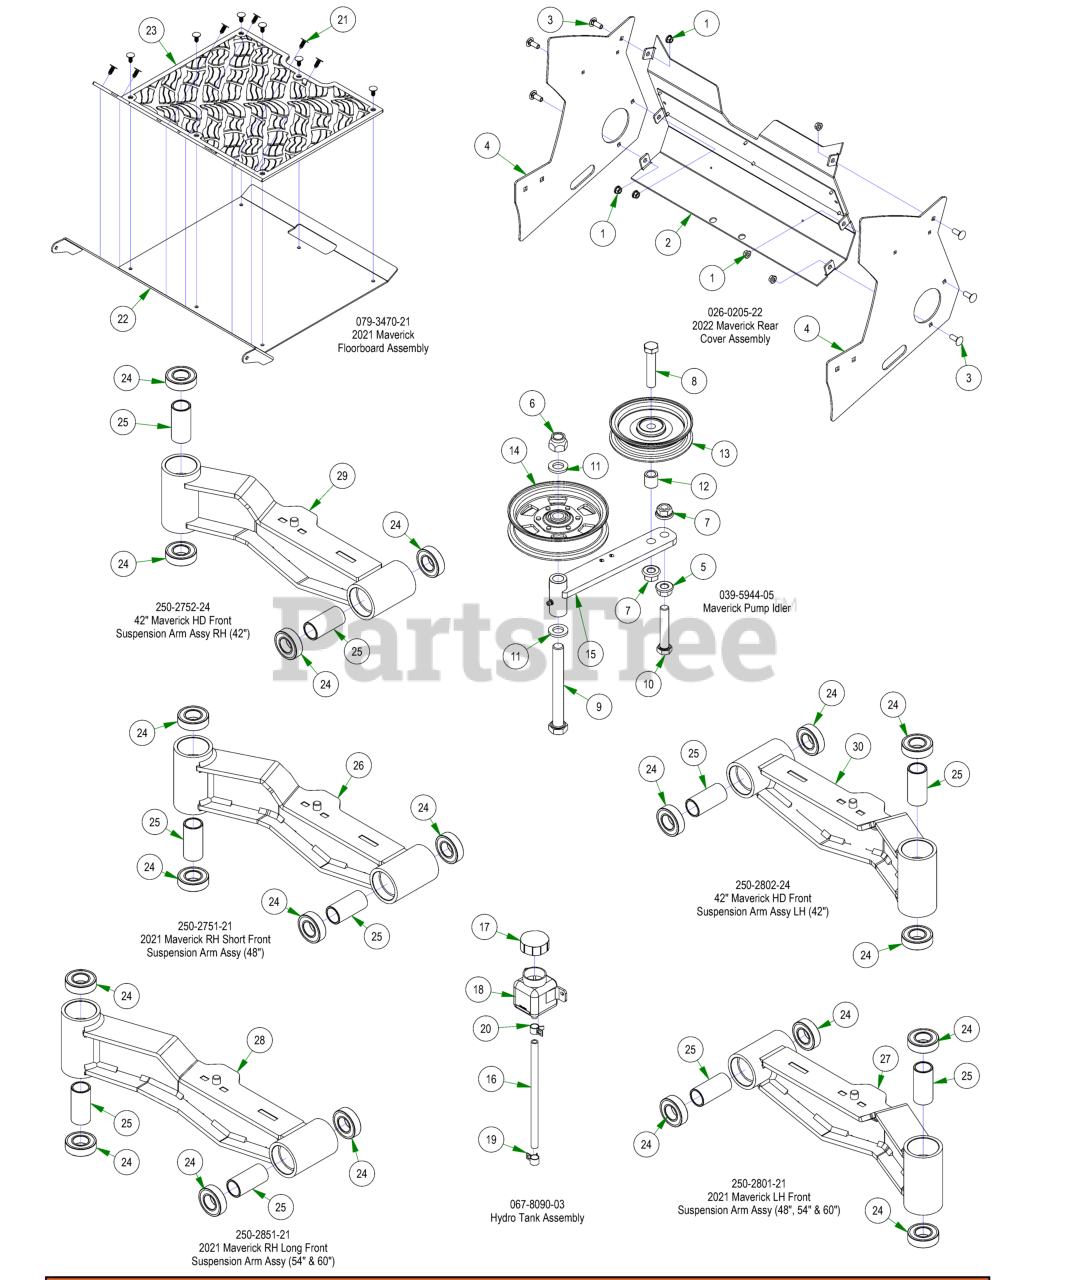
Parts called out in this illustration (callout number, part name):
1	5/16-18 NYLON INSERT FLANGE LOCKNUT ZINC
2	2021 Maverick Rear Cover Assembly
3	3/8-16 X 1 CARRIAGE BOLT (GR.5) ZINC
4	2022 Maverick Rear Cover Side Plate - Painted
5	1/2-13 HEX SERRATED FLANGE NUT HARD/ZINC
6	5/8-11 NYLON INSERT LOCKNUT ZINC
7	1/2-13 NYLON INSERT FLANGE LOCKNUT ZINC
8	1/2-13 X 2-1/2 HEX CAP SCREW GR 5 ZINC
9	5/8-11 X 5-1/2 HEX CAP SCREW (GR.5) ZINC
10	1/2-13 X 2-3/4 HEX CAP SCREW (GR.5) ZINC
11	.635 ID X 1.120 OD X .140 THICK FLAT WASHER NYLON
12	.51 ID X .75 OD X .75 LGTH SOLID SPACER ZINC
13	4 3/4" Idler Pulley
14	5 3/4 Idler Pulley, 5/8 Bore
15	Deck Idler
16	ZT/Maverick Hydro Tank Hose
17	Hydraulic Tank Cap
18	350ml Expansion Tank
19	3/8" Hose Clamp
20	1/2 Hose Clamp
21	Ratchet Fastener
22	2018 Maverick Floorboard
23	2021 Maverick Floor Mat W/ Reaper Tread
24	1641 BEARING W/2 CONTACT RUBBER SEALS
25	2016 Front Bearing Spacer
26	2021 Maverick I-Beam Front Arm RH Short Weldment - Painted
27	2021 Maverick I-Beam Front Arm LH Weldment - Painted
28	2021 Maverick I-Beam Front Arm RH Long Weldment - Painted
29	2022 42" Maverick I-Beam Front Arm - RH - Painted
30	2022 42" Maverick I-Beam Front Arm - LH - Painted
